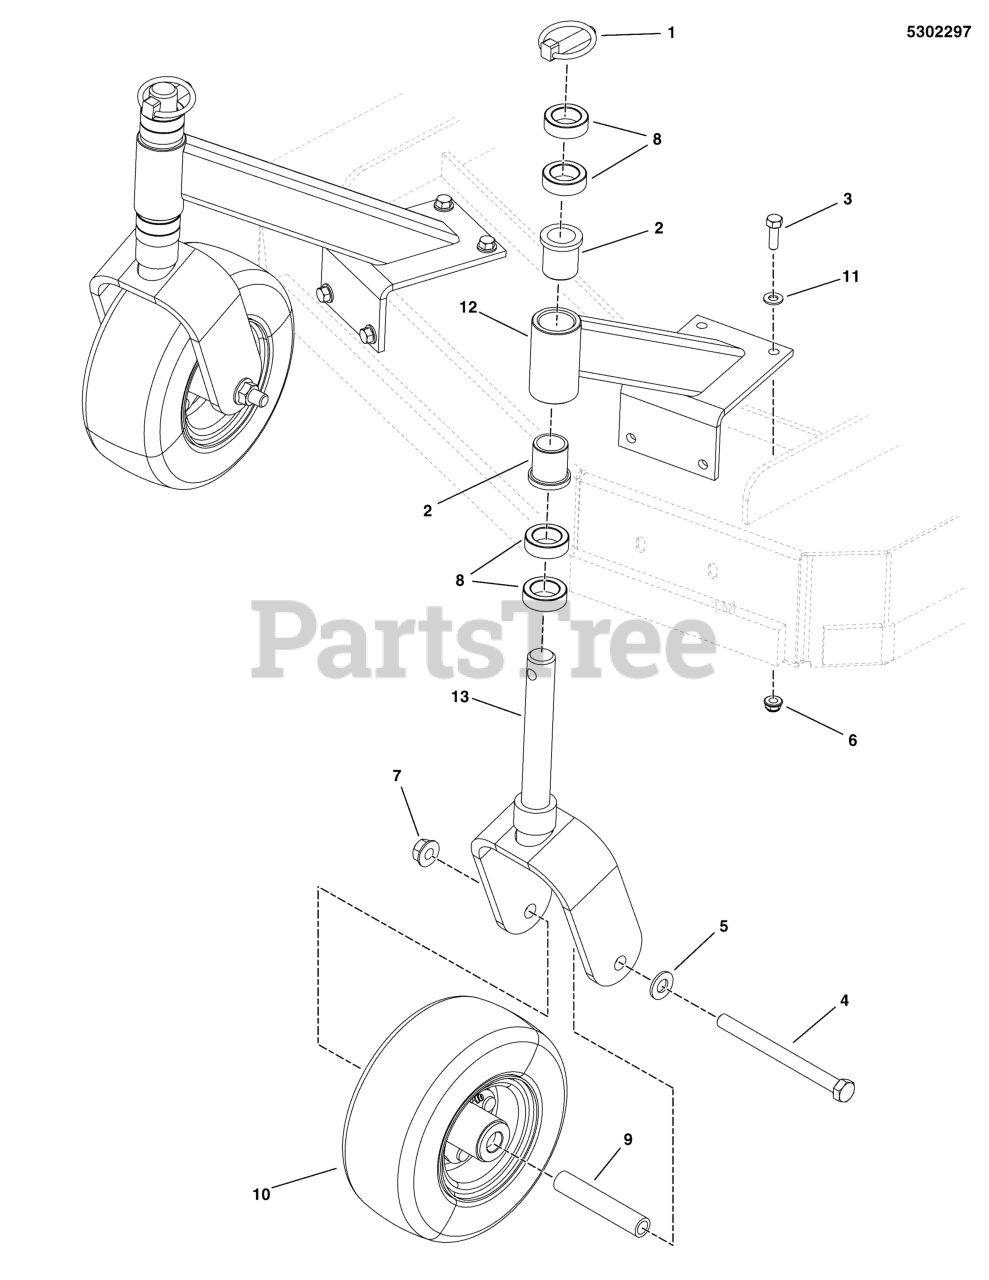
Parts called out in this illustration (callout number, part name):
1	PIN, LYNCH, 7/16
2	BUSHING, FLANGE
3	BOLT, 5/16-18 X 1 GD5 YZ
4	BOLT, 1/2-13 X 6 GD5 YZ
5	WASHER, 1/2 SAE
6	NUT, 5/16-18 HEX NYLOCK FLANGE
7	NUT, Hex Flange, Nylock, 1/2-13
8	SPACER, 1.02 X 1.56 X .50
9	AXLE, CASTER WHEEL
10	FLAT FREE TIRE ASSY, 9.00 X 3.50 - 4.00
11	WASHER, 5/16" SAE
12	ASSM, CASTER ARM, SW5
13	WELD, CASTER WHEEL MOUNT - RED
